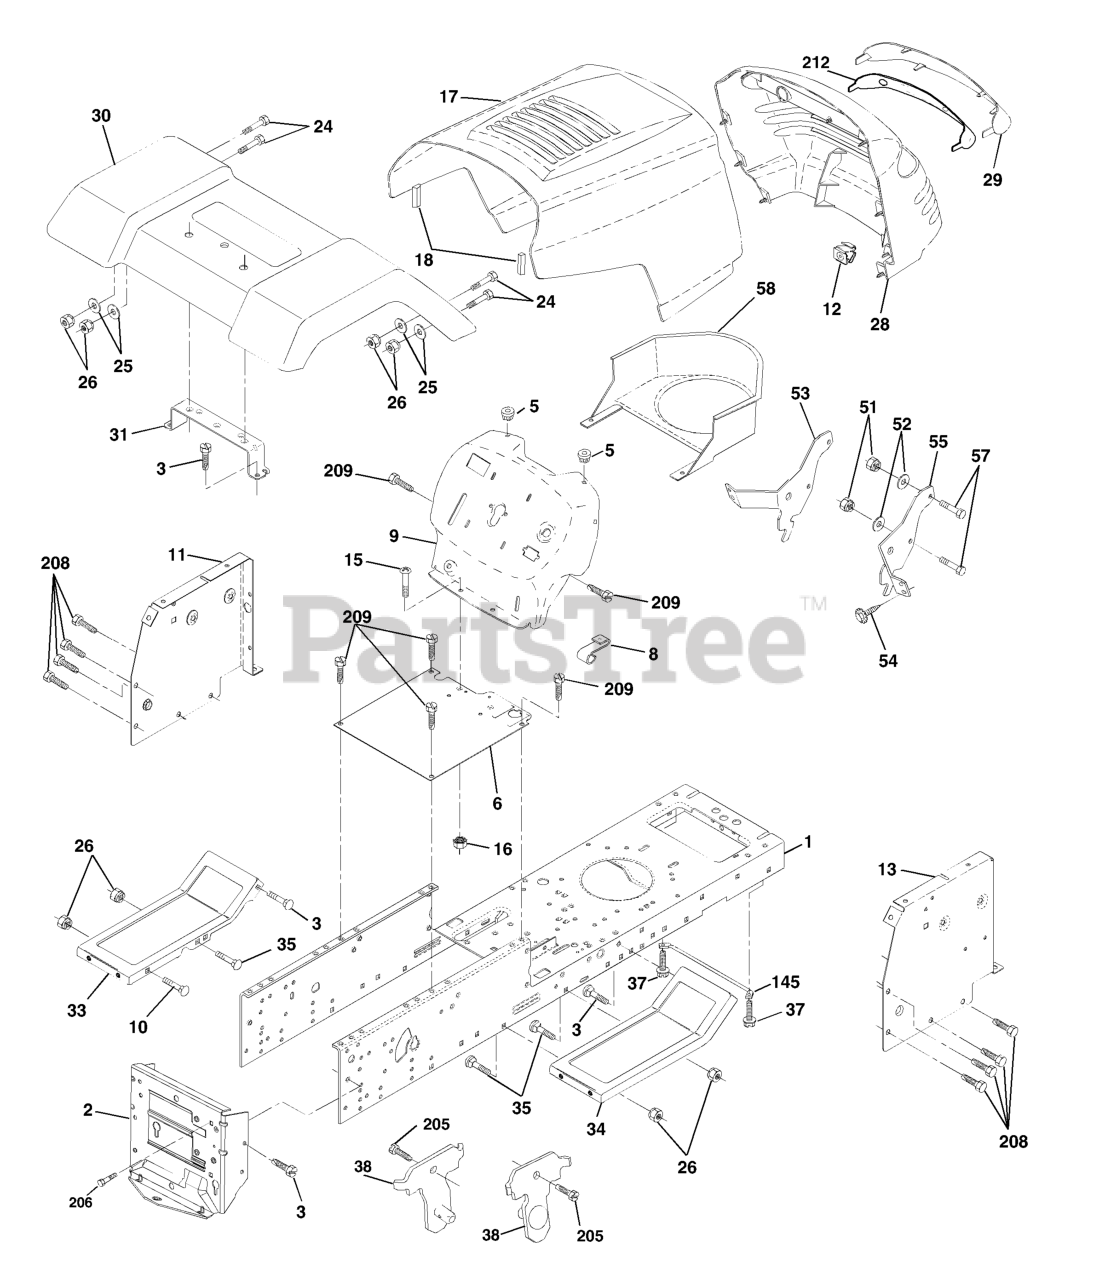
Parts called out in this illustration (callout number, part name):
2	DRAWBAR, 12GA
3	SCREW 3/8-16X3/4
5	BUMPER.RUBBER.HOOD
6	SADDLE FLAT
8	CLIP RETAINER
10	BOLT D
11	PANEL DASH LH
13	PANEL DASH RH
15	Screw Mach TRHD 5/16-18uncx3/4
16	NUT
17	HOOD ASM.
18	BUMPER HOOD T
24	BOLT
25	WASHER
26	NUT
28	GRILLE/LENS ASM.
29	LENS P/L
30	FENDER
31	BRACKET FENDER
33	FOOTREST PNT LH
34	FOOTREST PNT RH
35	BOLT
37	Screw Thdrol 5/16-18 x 1/2 TYT
38	BRACKET.ASM.PIVOT.MOWER.REAR
51	LOCKNUT.NYLOC.1/4-20
52	WASHER
53	BRACKET.GRILLE.LH
54	SCREW.HEX.WS.HD.8-18 X 7/8
57	BOLT
58	AIR DUCT P/L/LT
145	ROD PIVOT CHASSIS/HOOD
205	SCREW LT
206	SHOULDER BOLT 5/16-18TT
208	SCREW 3/8-16X1/2
209	SCREW, 3/8-16X3/4
212	REPL BY 532 1745-03
